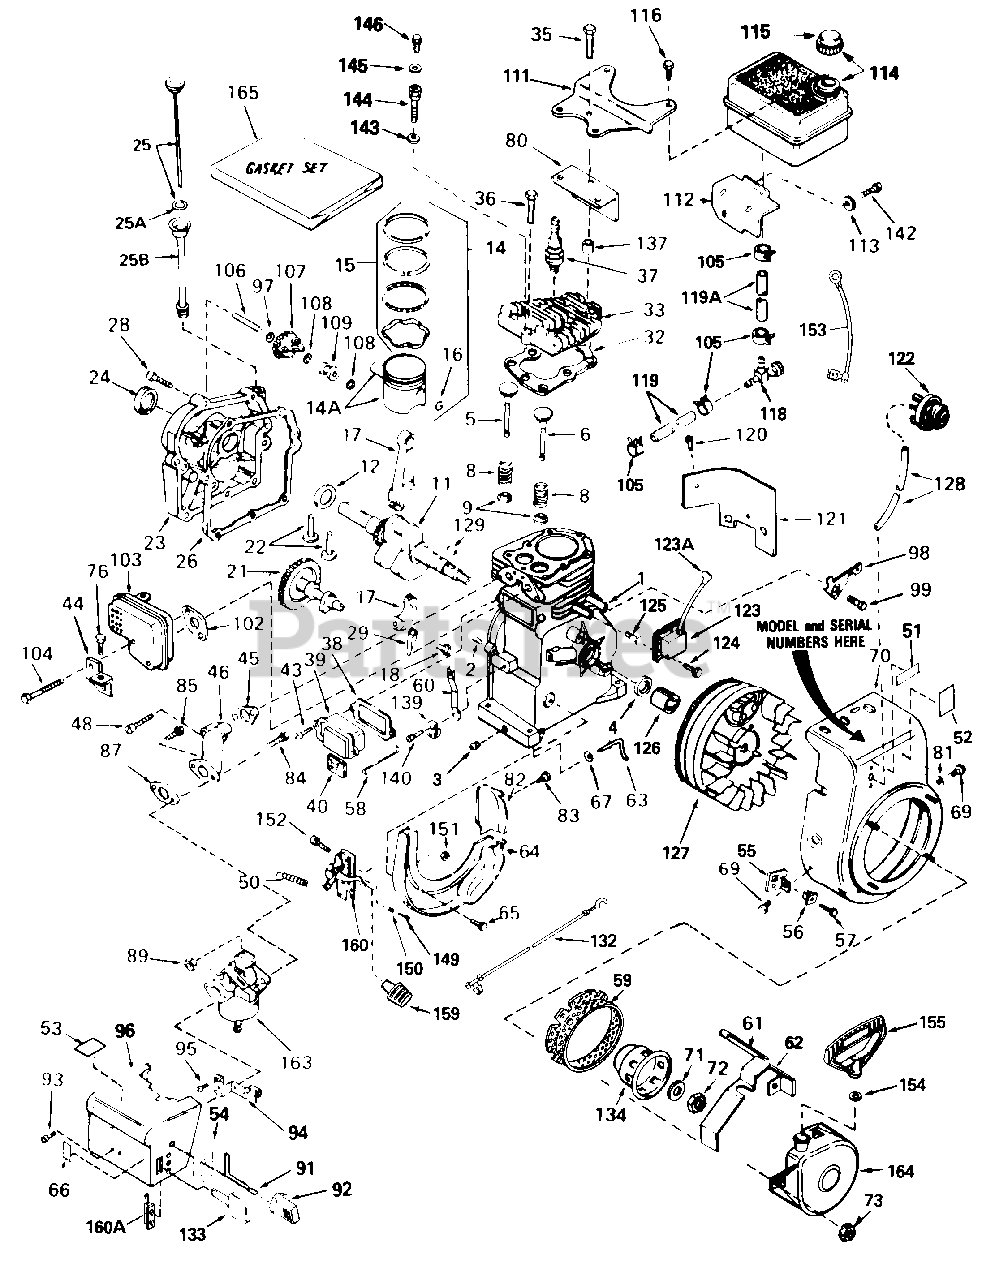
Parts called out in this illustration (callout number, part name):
1	Cylinder Ass'y.
2	Pin, Dowel
3	Plug, Sq. Hd. Pipe (Oil Drain) 1/4-18
4	Seal, Oil
5	Valve, Intake (Std.)
6	Valve, Exhaust (Std.)
8	Spring, Valve
9	Cap, Lower Valve Spring
11	Crankshaft
12	Washer, Thrust
14	Piston, Pin & Ring Ass'y. (Std.)
14A	Piston & Pin Ass'y. (Std.)
15	Ring Set, Piston (Std.)
16	Ring, Piston Pin Retaining
17	Rod Ass'y., Connecting
18	Bolt, Connecting Rod
21	Camshaft (Compression Release)
22	Lifter, Valve
23	Cover, Cylinder
24	Seal, Oil
25	Dipstick, Oil
25B	Tube, Oil Fill
26	Gasket, Cylinder Cover
28	Screw, Hex Hd. Sems, 1/4-20 x 1 1/4
29	Dipper, Oil
32	Gasket, Cylinder Head
33	Head, Cylinder
35	Screw, Hex Flange Hd., 5/16-18 x 2
36	Screw, Hex Flange Hd., 5/16-18 x 1 1/2
37	Spark Plug (Champion J-8C or Equivalent)
38	Gasket, Valve Spring Cover
39	Breather Ass'y.
40	Element, Breather
43	Screw, Fil. Hd. Sems, 10-24 x 1/2
44	Bracket, Carburetor Cover
45	Gasket, Intake Pipe
46	Pipe, Intake
48	Screw, Fil. Hd. Sems 1/4-20 x 1-19/32
50	Spring, Extension
51	Decal, Primer (Bilingual)
52	Decal, Name.
53	Decal, Warning (Bilingual)
54	Decal, Instruction (Bilingual)
55	Bracket, Grommet Mounting
56	Grommet, Plastic
57	Screw, Pan Hd. Self-Tap, 8-18 x 3/8
58	Link, Governor-to-Throttle
59	Screen, Starter Cup
60	Lever, Governor
61	Seal, Snow Guard
62	Guard, Starter
63	Rod, Governor
64	Baffle, Blower Housing
65	Screw, Hex Washer Hd. Durlok 1/4-20 x 5/8
66	Decal, Instruction
67	Washer, Flat
69	Screw, Hex Hd. Sems, 1/4-28 x 7/16
70	Housing, Blower
71	Washer, Belleville
72	Nut, Flywheel
73	Nut & Lockwasher, 1/4-28
76	Screw, Hex Hd. Sems, Taptite, 10-24 x 3/8
80	Baffle, Heat
81	Washer, Flat
82	Extension, Baffle
83	Screw, Hex Washer Hd. Shakeproof, Self-Drilling, 8-18 x 7/16
84	Screw, Hex Hd., 1/4-28 x 7/8
85	Screw, Hex Hd., 1/4-28 x 1-11/16
87	Gasket, Carburetor
89	Nut & Lockwasher, 1/4-28
91	Rod, Choke
92	Knob, Choke
93	Screw, Pan Hd. Sems, 8-32 x 5/16
94	Bracket, Choke
95	Screw, Fil. Hd. Sems, 10-32 x 1/2
96	Cover, Carburetor
97	Washer, Flat
98	Bracket, Hold Down
99	Screw, Hex Washer Hd. Self-Tap Sems, 10-24 x 9/16
102	Gasket, Muffler
104	Screw, Fil. Hd. Sems, 1/4-20 x 2-1/2
105	Clamp, Fuel Line
106	Shaft, Mechanical Governor
107	Gear Ass'y., Governor
108	Ring, Retaining
109	Spool, Governor
111	Plate Fuel Tank Mounting
112	Bracket, Fuel Tank Mounting
113	Washer, Flat
114	Tank Ass'y., Fuel
115	Cap, Fuel Tank
116	Screw, Hex Washer Hd. Self-Tap Sems, 1/4-15 x 7/8
118	Valve, Shut-Off
119	Line, Fuel
119A	Line, Fuel
120	Screw, Fil. Hd. Sems, 10-24 x 1/2
121	Extension, Blower Housing
122	Primer Ass'y.
123	Solid State Ass'y.
123A	Cover, Spark Plug
124	Screw, Hex Hd. Sems, 10-24 x 1
125	Stud, Solid State Mounting
126	Spacer, Flywheel Key
127	Flywheel (w/Ring Gear)
128	Line, Primer
129	Key, Flywheel
132	Wire, Ground
133	Key, Ignition
134	Cup, Starter
139	Clamp, Governor Lever
140	Screw, Hex Washer Hd., 8-32 x 5/16
142	Screw, Hex Hd. w/Belleville Washer, 1/4-20 x 11/16
143	Washer, Flat
144	Screw, Special Hex Hd., 5/16-18 x 11/2
145	Washer, Flat
146	Screw, Hex Hd. Sems, 1/4-20 x 1/2
149	Screw, Fil. Hd., 5-40 x 7/16
150	Spring, Compression
151	Locknut, Hex "Keps" 8-32
152	Screw, Fil. Hd. Sems, 8-32 X 1/2
153	Wire, Ground
154	Washer, Flat
155	Handle, Mitten Grip Starter
159	Knob, Control
160	Bracket Ass'y., Control
160A	Terminal Ass'y.
163	Carburetor
164	Starter Ass'y., Rewind
165	Gasket Set
